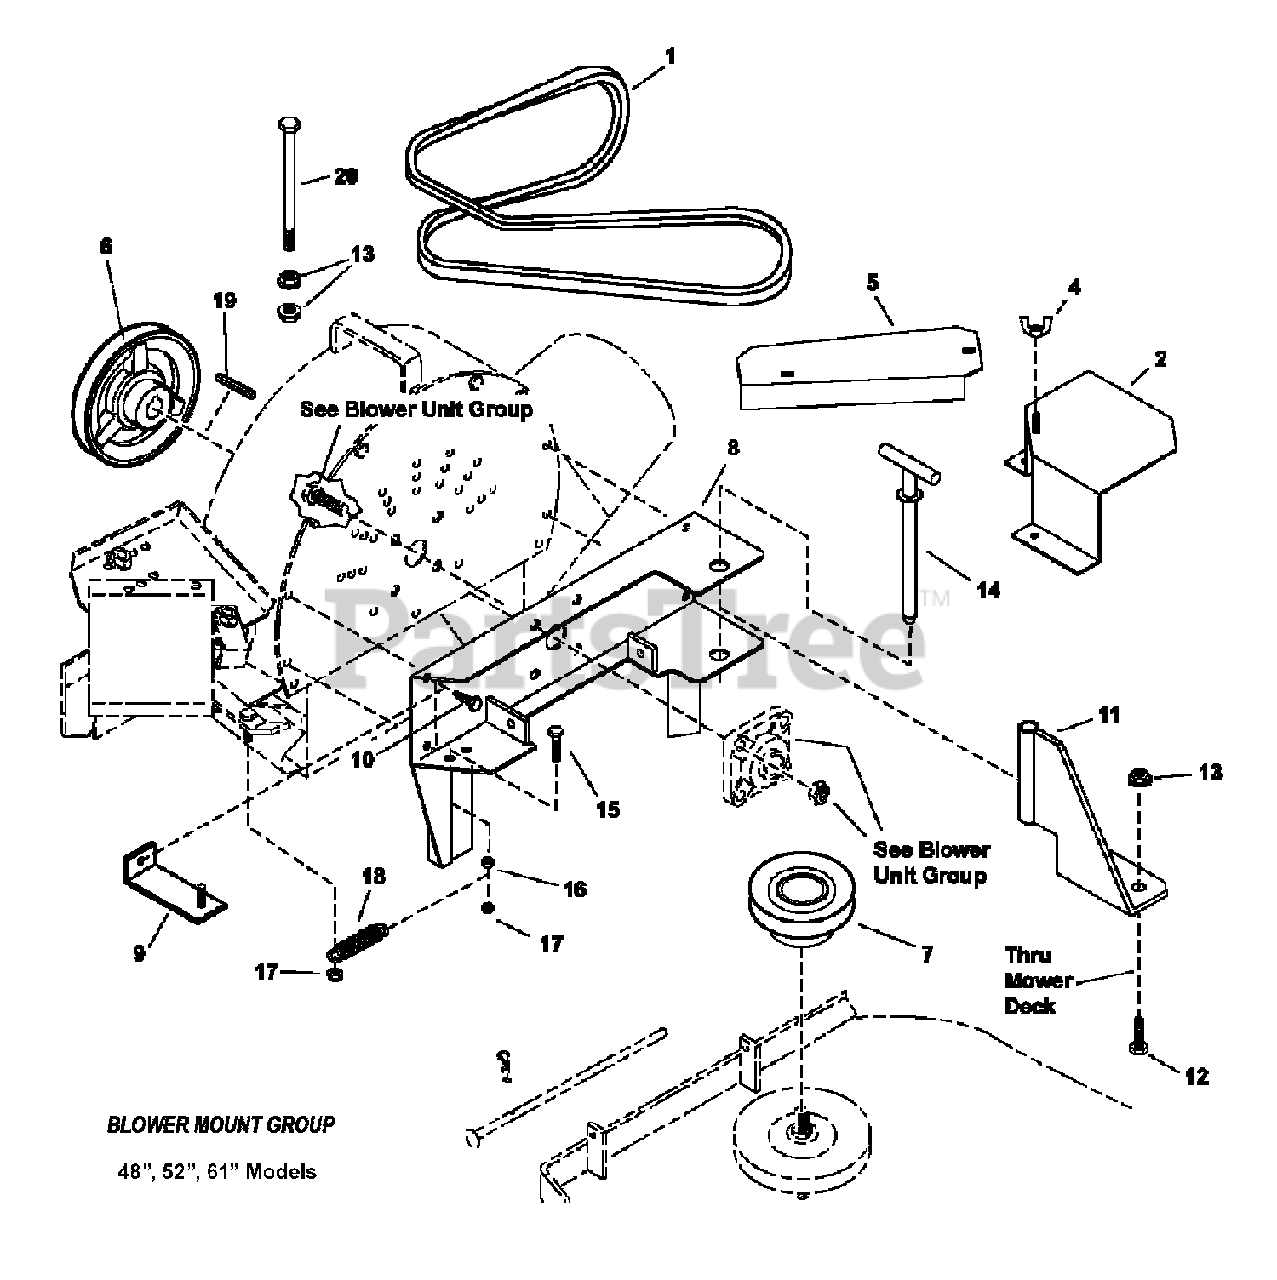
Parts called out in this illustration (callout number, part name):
1	BELT, A Section, 91.125" effective length (used on 48 & 52 Models)
1	BELT, A Section, 92.0" effective length (used on 61 Models)
2	WELDMENT, Belt Cover, Deck (used on 48 & 52 Models)
2	GUARD, Pulley
4	WING LOCKNUT 5/16-18
5	BELT GUARD, 48" Deck
5	BELT GUARD, 52" Deck
5	BELT GUARD, 61" Deck
6	PULLEY, Blower Input, 48" & 52"
6	PULLEY, Blower Input, 61"
7	PULLEY, 48"/52" Spindle
8	WELDMENT, 48" Blower Mount
8	WELDMENT, 52" Blower Mount
8	WELDMENT, 61" Blower Mount
9	WELDMENT, Guard Support Bracket
10	SCREW, 5/16-18 x 3/4" Hex Washer Self-Tap
11	WELDMENT, Deck Mount Bracket
12	SCREW, 3/8-16 x 1" Hex Head Cap, GR5
13	NUT, 3/8-16 Hex Flange Lock
14	WELDMENT, T-Handle Pin
15	SCREW, 5/16-18 x 1-1/4" Hex Head Cap, GR5
16	NUT, 5/16-18 Hex Flange Lock
17	NUT, 5/16-18 Hex Large Flange Center Lock
18	SPRING, Idler, Fast Vac
19	KEY, 1/4 Square x 1.44
20	SCREW, 3/8-16 x 6" Hex Head Cap, GR5
